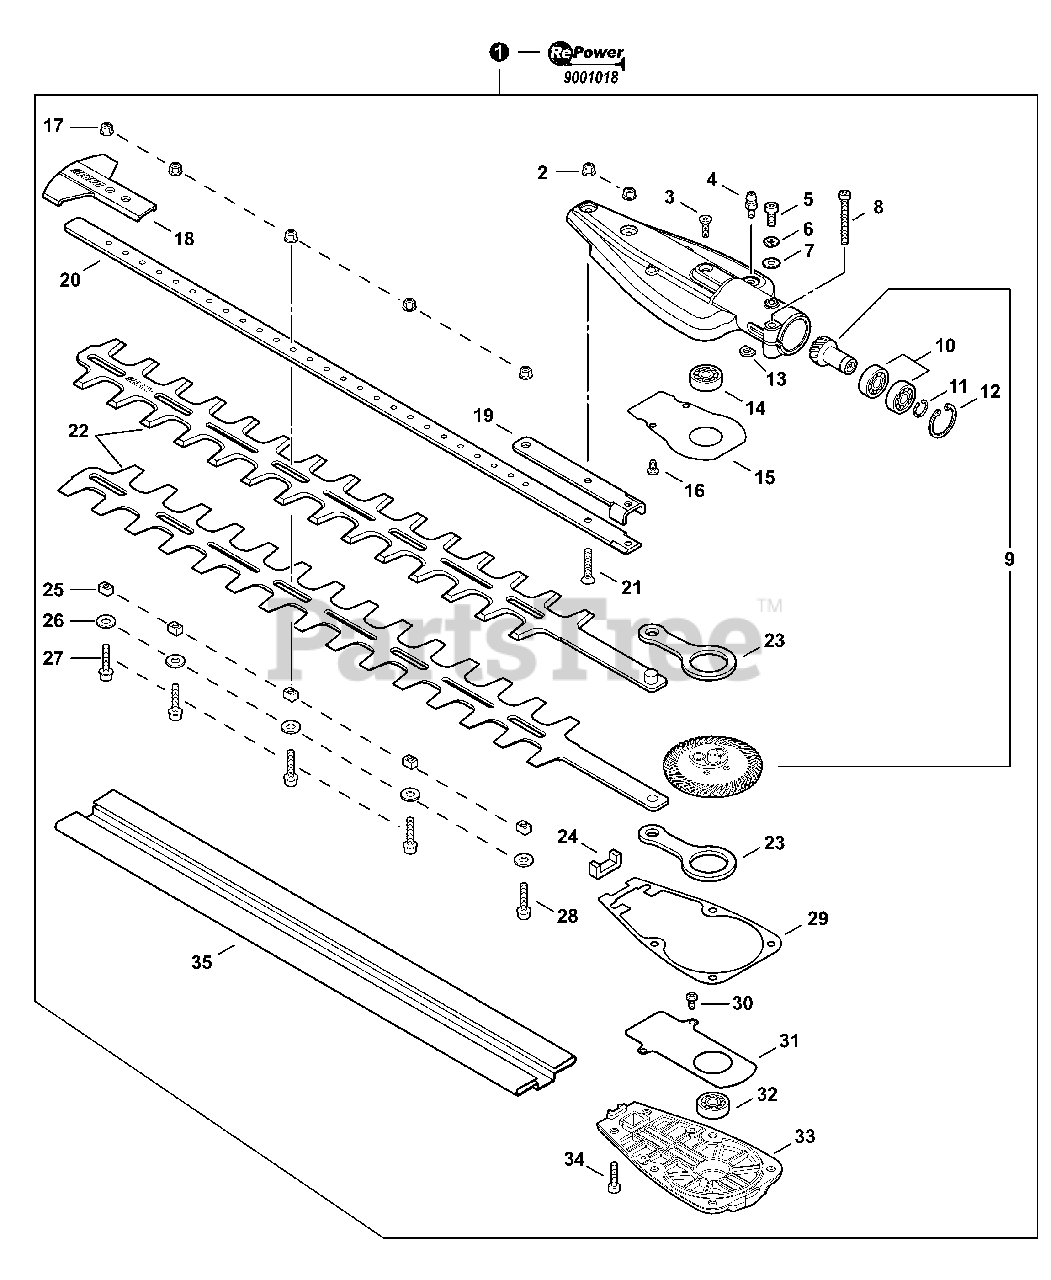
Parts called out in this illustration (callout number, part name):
1	TRIMMER HEAD ASY
2	LOCKNUT - 5
3	SCREW - 5×8
4	FITTING, GREASE
5	SCREW - 5×12
6	WASHER, SPRING 5
7	WASHER, FLAT 5.5×10×0.8
8	SCREW - 5×25
9	GEAR, BEVEL SET
10	BEARING, BALL - 6901
11	RING, RETAINING - 12
12	RING, RETAINING - 24
13	WASHER, SHIM
14	BEARING, BALL - 608ZZ
15	PLATE, WEAR
16	SCREW - 4×5
17	LOCKNUT - 5
18	GUARD, TIP
19	SUPPORT, BLADE
20	SUPPORT, BLADE
21	SCREW - 5×18
22	BLADE, TRIMMER
23	ROD, CONNECTING
25	GUIDE, BLADE
26	WASHER - 6
27	SCREW - 5×20
28	SCREW - 5×22
29	GASKET, GEAR CASE
30	SCREW - 4×5
31	PLATE, WEAR
32	BEARING, BALL - 628ZZ
33	LID, GEAR CASE
34	SCREW - 5×12
35	COVER, BLADE
